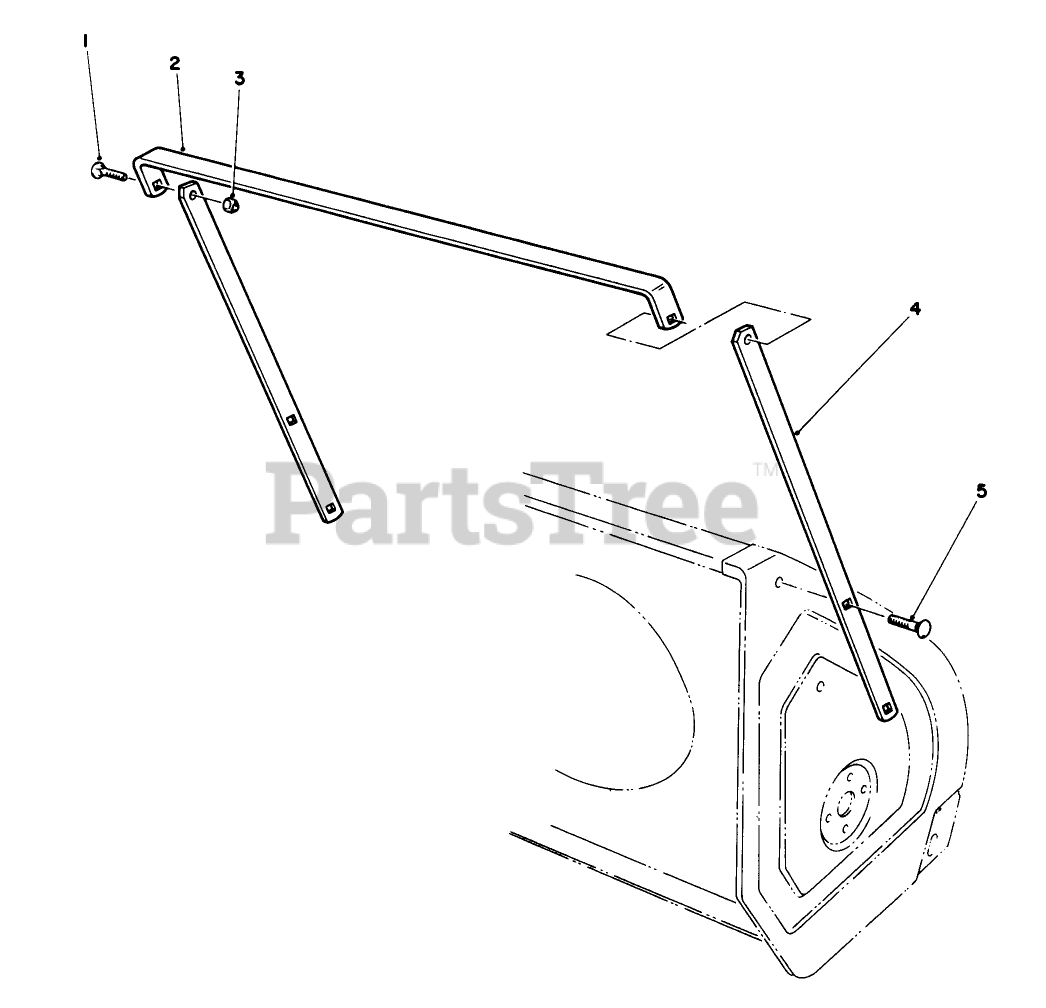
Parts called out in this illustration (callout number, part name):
1	SCREW-CARR
3	NUT-LOCK, NI
4	Breaker-Side
5	BOLT-CARR
